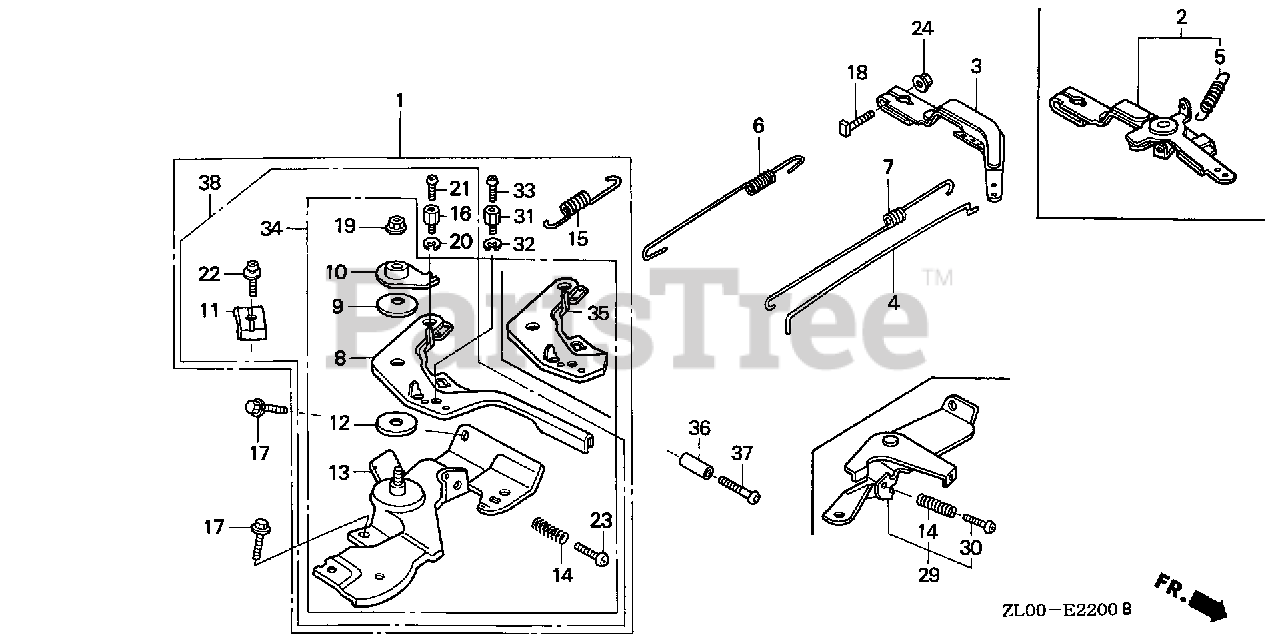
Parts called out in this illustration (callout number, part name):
1	CONTROL ASSY. (REMOTE)
3	ARM, GOVERNOR
4	ROD, GOVERNOR
6	SPRING, GOVERNOR
7	SPRING, THROTTLE RETURN
8	LEVER, CONTROL
9	SPRING, LEVER
10	WASHER, CONTROL LEVER
11	HOLDER, CABLE
12	SPACER, CONTROL LEVER
13	BASE, CONTROL (REMOTE)
14	SPRING, CONTROL ADJUSTING
15	SPRING, CABLE RETURN
17	BOLT, FLANGE (6X12) (CT200)
18	BOLT, GOVERNOR ARM
19	NUT, SELF-LOCK (6MM)
22	SCREW, PAN (5X16)
23	SCREW, PAN (5X25)
24	NUT, FLANGE (6MM)
